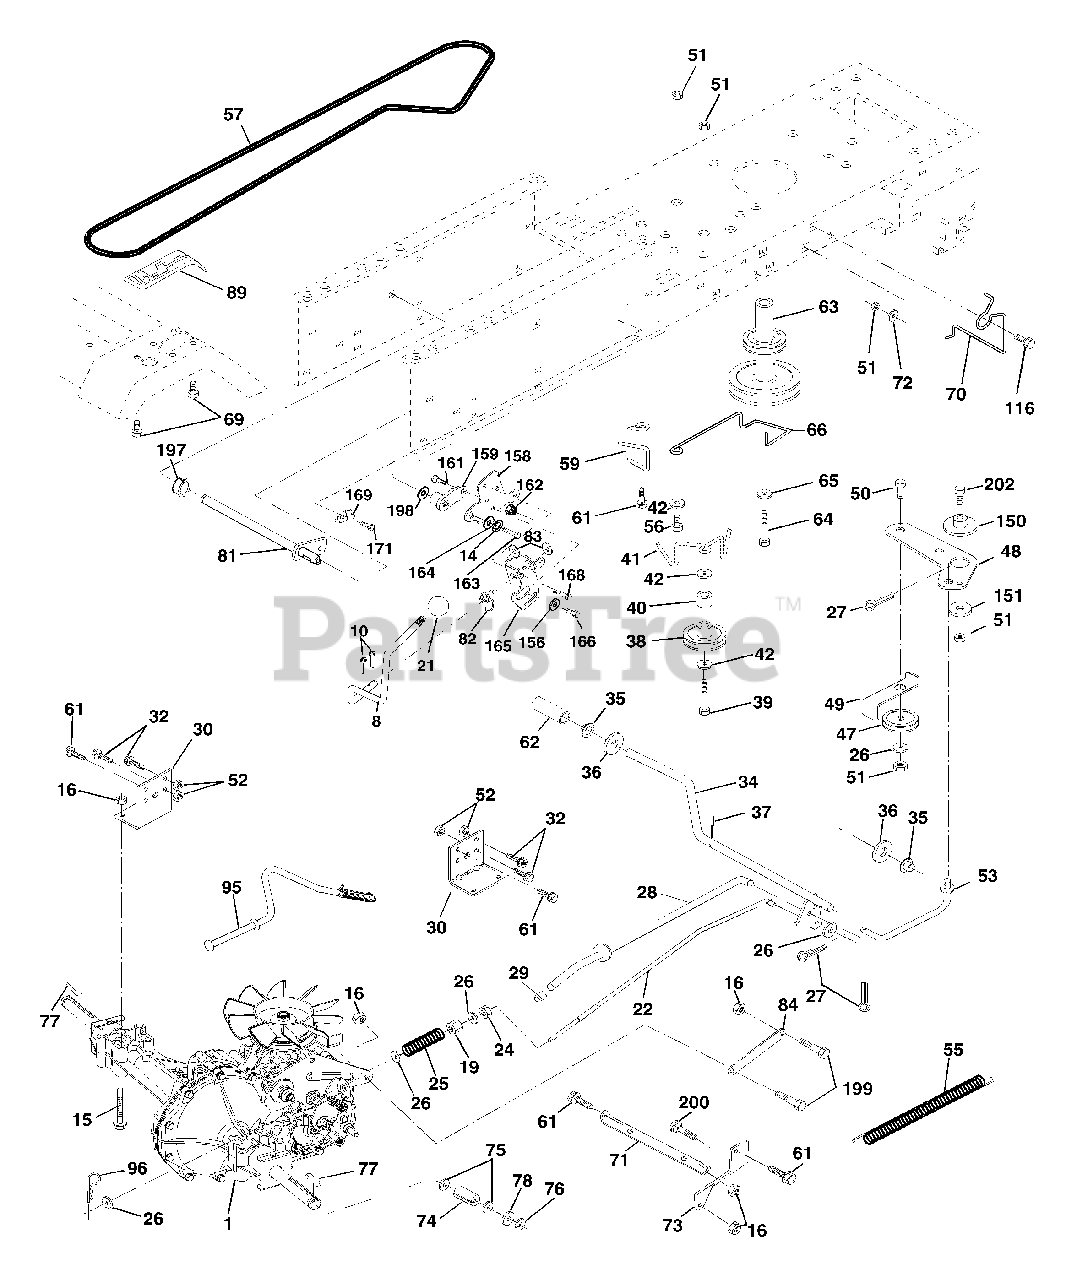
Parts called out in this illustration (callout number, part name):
8	Rod Shift Fender Adjust LT
10	Pin Cotter 1/8 x 1 CAD
14	Washer Lock Hvy Helical
15	Bolt, Hex FLGHD 5/16-18 Gr. 5
16	Nut Lock Hex W/Ins 5/16-18 Unc P
19	Nut Lock Hex W/Wsh 3/8-16 Unc
21	Knob, Round 1/2-13
22	Rod, Brake Hydro
24	Nut
25	Spring, Brake Rod
26	Washer
27	Pin Cotter 1/8 x 3/4 CAD.
28	Rod, Parking Brake
29	Cap, Parking Brake
30	Bracket, Transaxle
32	Bolt Hex Hd 5/16-18 Unc x 3/4
34	Shaft, Foot Pedal
35	Bearing, Nylon
36	Washer
37	Pin, Roll
38	Pulley, Idler, Flat
39	Bolt
40	Spacer, Split
41	Keeper, Belt Idler
42	Washer 13/32 x 13/16 x 12 Gauge
47	Pulley, Idler, V-Groove
48	Bellcrank Clutch Grd Drv Stl
49	Retainer, Belt
50	Bolt
51	Nut Crownlock 3/8-16 UNC
52	Nut Crownlock 5/16-18 UNC
53	Link, Clutch
55	Spring, Return, Clutch
56	Bolt Fin Hex 3/8-16 UNC x 1-1/4
57	V-Belt, Ground Drive
59	Keeper, Center Span
61	Screw 3/8-16 x 3/4
62	Cover, Pedal
63	Pulley, Engine
64	Bolt, Hex
65	Washer
66	Keeper Belt Engine Hydro
69	Screw
70	Keeper Belt Engine
71	Strap Torque Lh Hydro
72	Washer 13/32 x 1-1/4 x 12 Gauge
73	Strap Torque Rh Hydro
74	Spacer, Axle
75	Washer 25/32 x 1-1/4 x 16 Gauge
76	E-Ring
77	Key, Square
78	Washer 25/32 x 1-5/8 x 16 Gauge
81	Shaft Asm Cross Tapered
82	Spring Torsion T/A
83	Washer 17/32 x 3/4 x 16 Ga.
84	Link, Transaxle Hydro 0500
89	Console, Hydro
95	Control Asm Bypass Hydro
96	Retainer Spring 1" Zinc/Cad
116	Bolt Rdhd Sq Neck 3/8-16 x 1.25
150	Bushing Bellcrank Grd Drive
151	Washer 13/32 x 2 x 10 Ga.
156	Washer Srrted 5/16 ID x 1.125
158	Bracket Shift Mount
159	Hub Tapered Flange Shift LT
161	Bolt Rdhd Sqnk 1/4-20 x 3/4 Gr. 5
162	Nut Crownlock 1/4-20 Unc
163	Bolt Hex Fin 1/4-20 Unc x 1 Gr. 5
164	Washer 5/8 x .281 x 10 Ga.
165	Bracket Pivot Lever
166	Screw 5/16-18 x 5/8
168	Bolt Shoulder 5/16-18 x .561
169	Plate Fastening LT
171	Screw Thdrol 3/8-16 x 1/2 TY-TT
197	Nyliner Snap-In 5/8" Id
198	Washer Nyl 7/8 Id x .105
199	Bolt Shoulder 5/16-18 Unc
200	Bolt Rdhd Sqnk 5/16-18 Unc x 1
202	Bolt Carr Sh 3/8-16 x 1-1/2 Gr. 5
